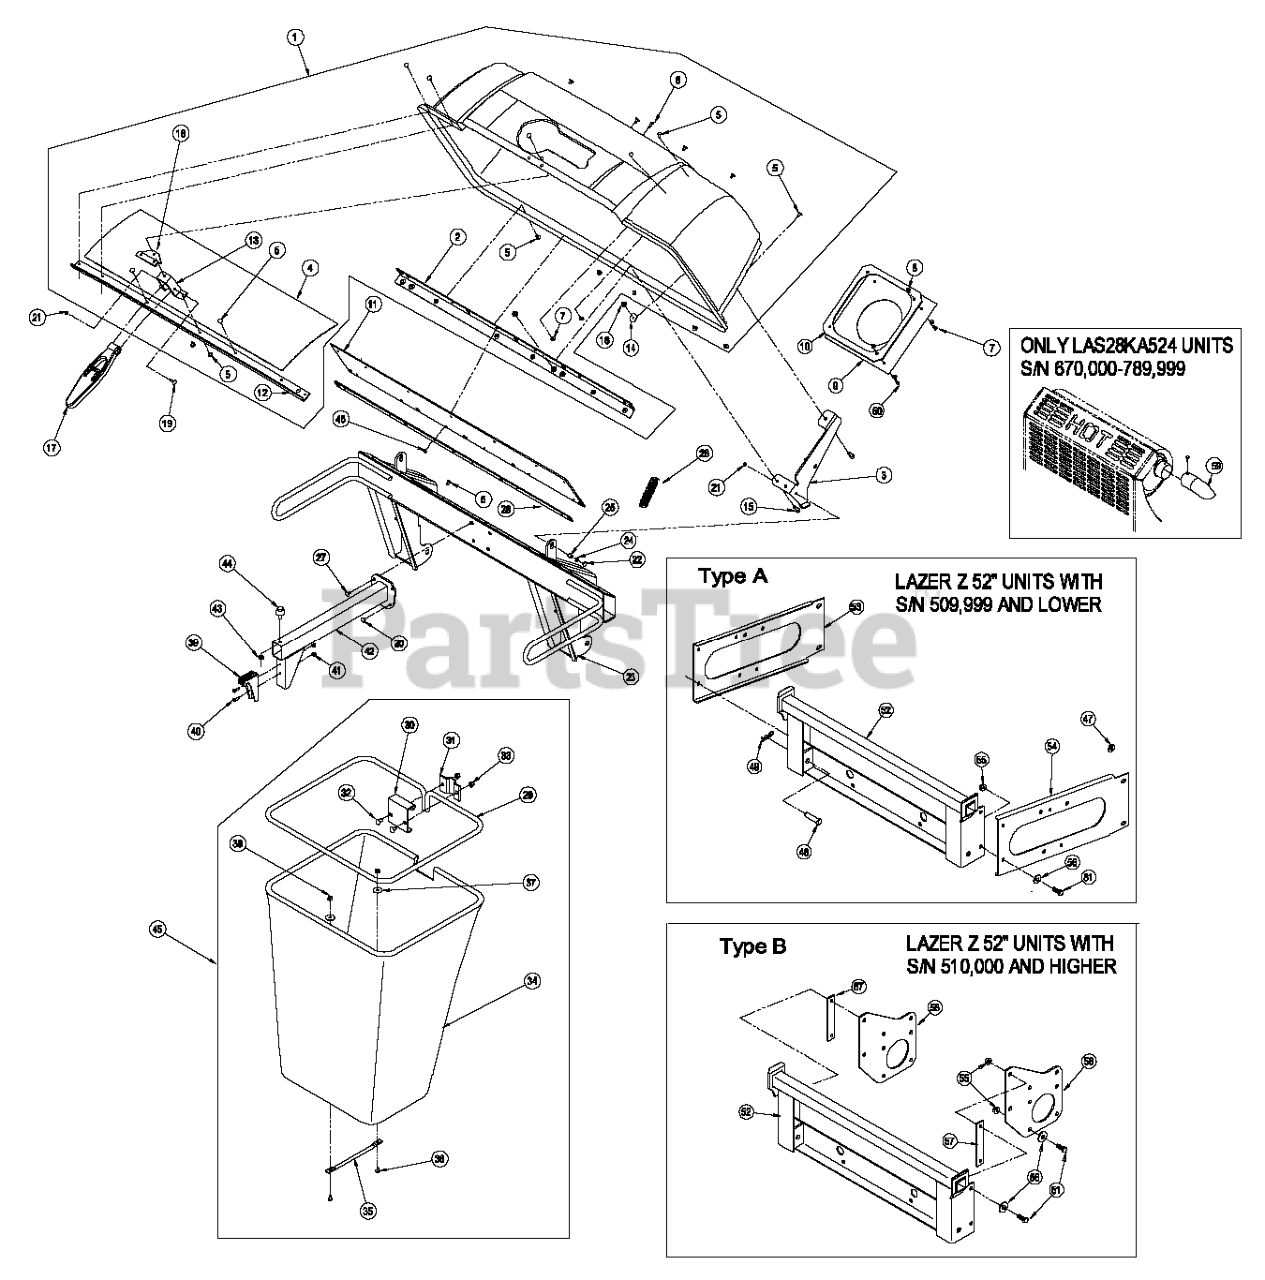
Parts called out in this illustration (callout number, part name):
1	ASM, HOOD
2	STIFFENER-BAGGER, TOP
4	SCREEN-BAGGER
5	RIVET-BLIND
6	SCREW-HEAD, TRUSS
7	WASHER-FLAT
8	NUT-LOCK, NI
9	SEAL-CHUTE
10	CLAMP-SEAL
11	SEAL-HOOD
12	SUPPORT-SCREEN
13	ANCHOR-LATCH
15	SCREW-HH
18	REINFORCEMENT-LATCH
19	SCREW-HH
20	SCREW-HSBH
21	NUT-LOCK, NI
22	SCREW-HH
23	UPRIGHT-BAGGER
24	WASHER-FLAT
26	SPRING-EXTENSION
27	SCREW-HH
28	PLATE-BACKING
29	FRAME-BAG
30	HANGER-BAG
32	BOLT-CARR
33	NUT-LOCK, NI
35	HANDLE-BAG
36	BOLT-CARR
38	NUT-LOCK, NI
40	SCREW-PPH
42	SUPPORT-BAG
45	BAG AND FRAME ASM
46	NUT-LOCK, SIDE
47	SPACER
48	PIN-CLEVIS
49	PIN-COTTER
50	SCREW-PPH
51	SCREW-HH
52	MOUNT-BAGGER
53	BRACKET-FRAME, LH
54	BRACKET-FRAME, RH
55	NUT-HHF, WHIZ
56	WASHER-BELLEVILLE
58	PLATE-MOUNT, BAGGER
59	TUBE,EXHAUST DEFLECTOR
